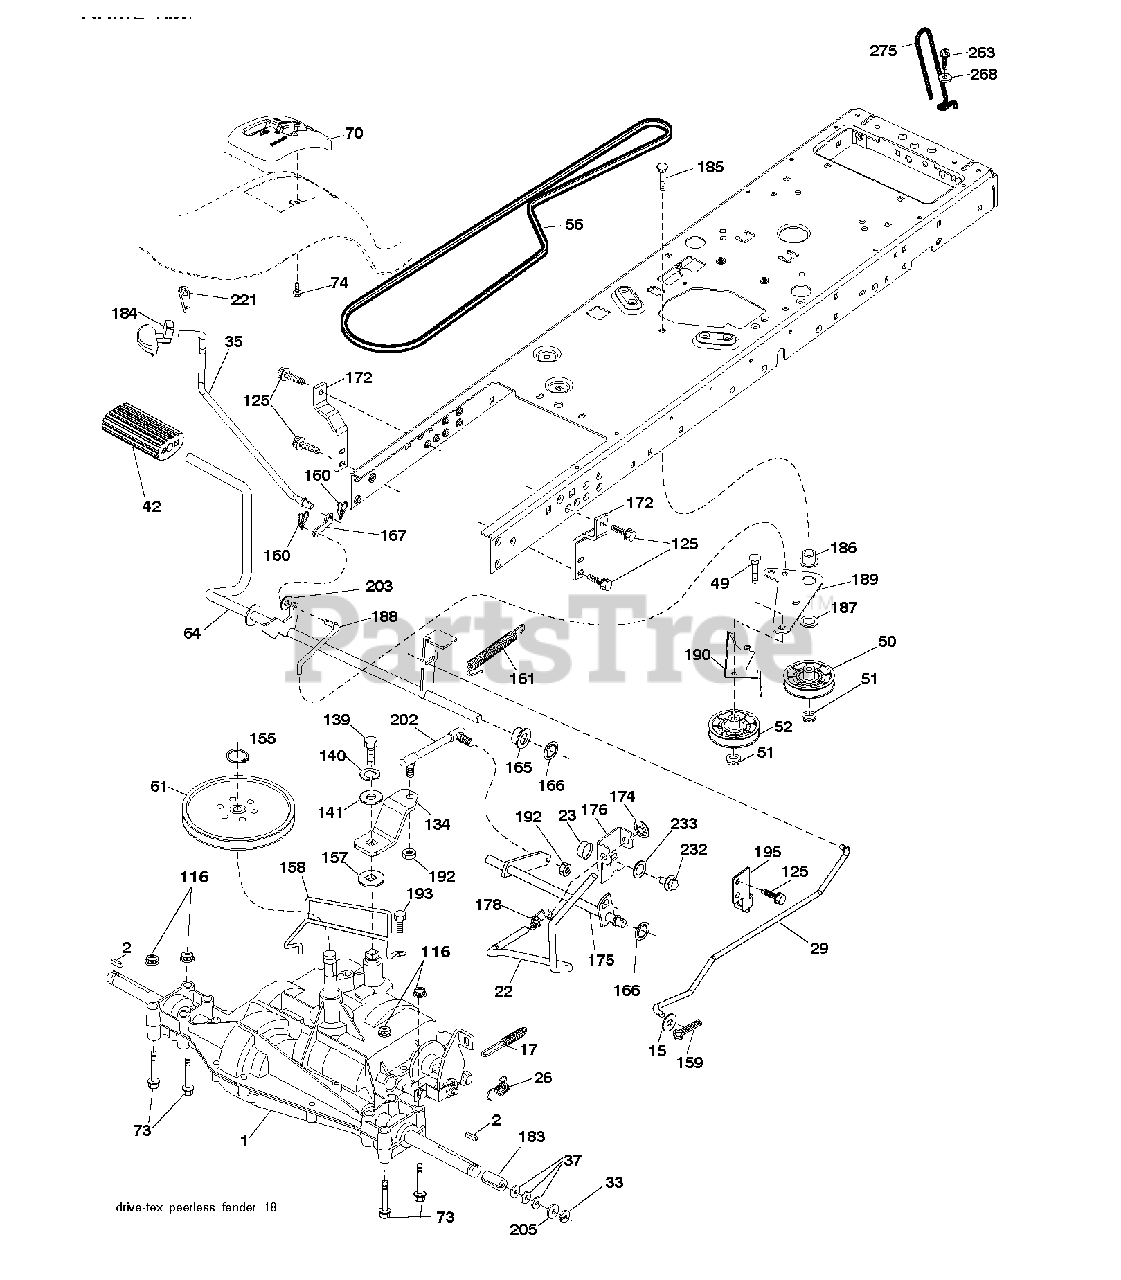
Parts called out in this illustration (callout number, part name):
2	SQUARE KEY
17	SPRING.BRAKE.PEERLESS.TEX
22	ROD.SHIFT.FENDER.TLT.2006
23	KNOB.DUCKHEAD.1/2
26	SPRING.BRAKE.RTN.GR.DR
29	ROD.BRAKE.PEERLESS
33	E-RING LT
35	ROD, BRAKE, PARK
42	PEDAL COVER T
49	BOLT
50	IDLER.FLAT.910.OFFSET
51	NUT LOCK FLG 3/8-16 UNC
52	IDLER.V-GROOVE.910.OFFSET
56	V-BELT.TRACTOR.DRIVE.P
61	PULLEY TRANS
64	SHAFT.ASM.PEDAL.BRAKE.
70	CONSOLE.SHIFT.
73	BOLT HEX 5/16-18 GR 5
74	SCREW.HI-LO.CONSOLE
116	NUT LOCK HEX FLANGE 5/16-18
125	SCREW
134	ARM SHIFT
139	BOLT 1/4-28X3/4
140	LOCKWASHER
141	WASHER LT
155	RETAINING RING LT
157	WASH-SHFT PLT LT
158	KEEPER.PMS.18/20.D4365
159	COTTER PIN
160	RETAINER CLIP
161	SPRING, RETURN LT
165	BUSHING.SHAFT.BRAKE.HAND
166	NUT.PUSH.625.2006
167	LATCH.BRAKE.SPRING
172	STRAP.TRQ.LH.GEAR.DRIV
174	NUT.PUSH.500.2006
175	SHAFT ASM SHIFT
176	ARM.CLEVIS.ROD.SHIFT
178	SPRING.SHIFT.GT2006
183	SPACER AXLE
184	HANDLE PARKING BRAKE
186	SPACER.RETAINER
187	WASHER 12/32X2X10GA
188	LINK.CLUTCH.GROUND.DRIVE
189	BELLCRANK.GROUND.DRIVE.TEX.
190	KEEPER.BELLCRANK.DRIVE
192	NUT LOCK CENTER 1/4 -28 FNTHD
193	SCREW 5/16"
195	BRKT.ROD.BRAKE.PEERLES
202	LINK.SHIFT.PMST.18"
203	WASHER
221	RETAINER.SPRING.CLIP.H
232	BOLT FIN HEX 7/16-14 X 1
233	WASHER SERRATED
263	SCREW, 3/8-16X3/4
268	WASHER
